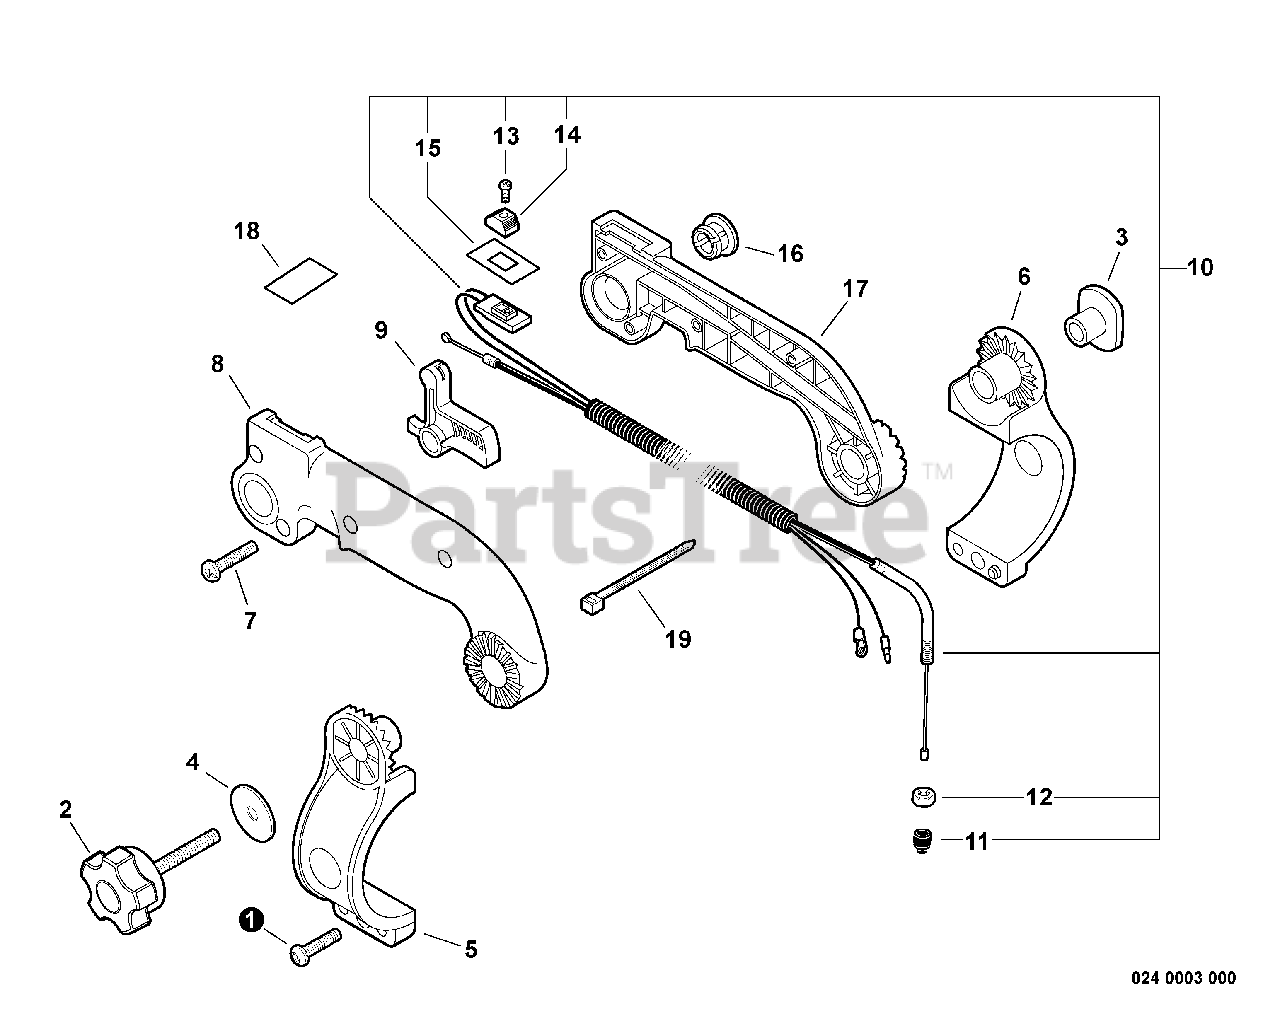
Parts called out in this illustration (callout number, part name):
1	SCREW - 5X20 -- TAPPING
2	THUMBSCREW
4	WASHER - 6
5	BRACKET, HANDLE - LEFT
6	BRACKET, HANDLE - RIGHT
7	SCREW - 4X22
8	HANDLE, FRONT - LEFT
9	TRIGGER, THROTTLE
10	CONTROL CABLE ASSY
11	CAP, DUST
12	LOCKNUT - 6
13	SCREW - 3X10
14	KNOB, SWITCH - ORANGE
15	COVER, SWITCH - STOP
17	HANDLE, CONTROL - RIGHT
18	LABEL - IDLE
19	TIE, CABLE - LARGE
